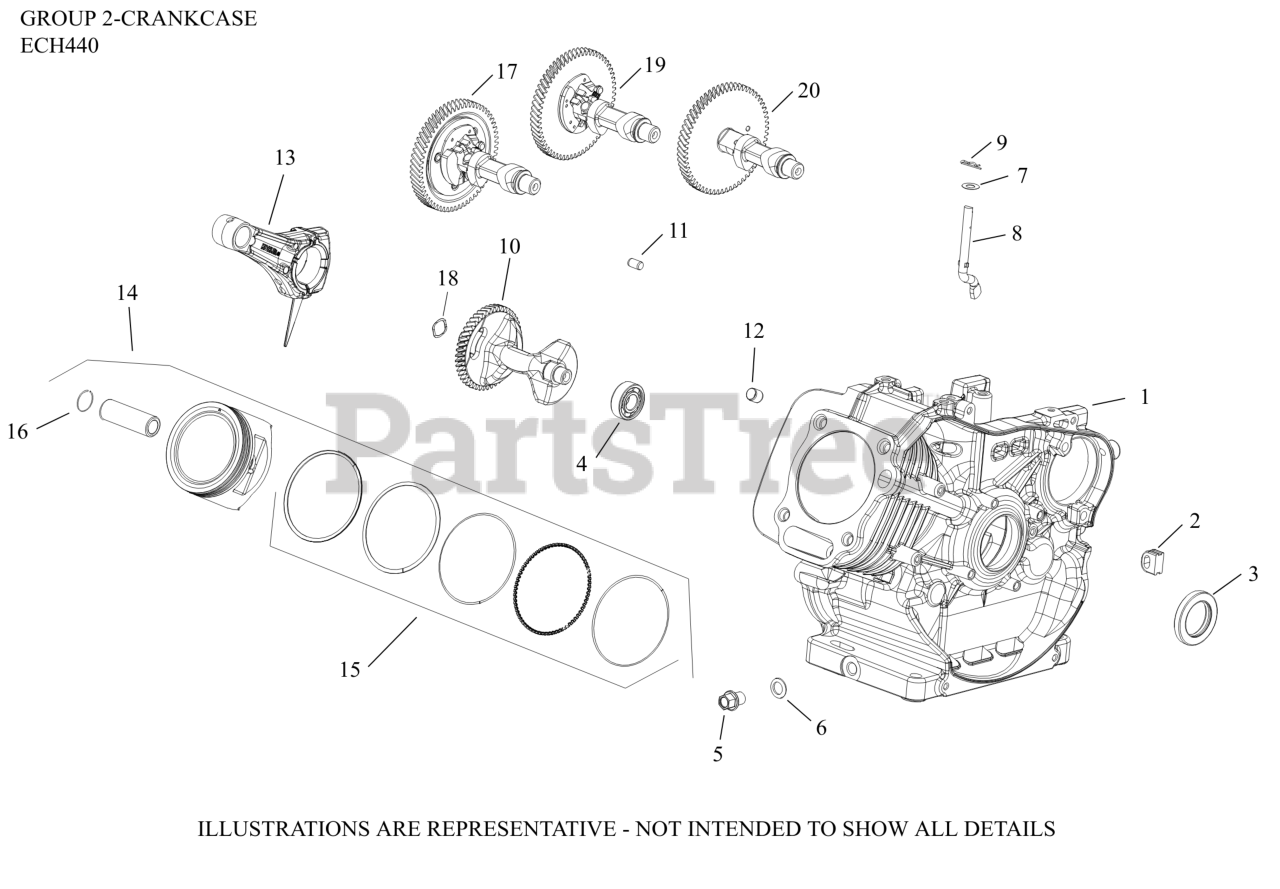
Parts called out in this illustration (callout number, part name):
2	GROMMET, CRANKCASE
3	SEAL, CRANKSHAFT
4	BEARING, BALANCE SHAFT
5	KIT, DRAIN PLUG
6	WASHER, DRAIN PLUG
10	SHAFT, BALANCE
11	PIN, DOWEL
12	PIN, DOWEL CYLINDER HEAD
13	ROD, CONNECTING ASSEMBLY
14	KIT, PISTON W/RING SET (STD)
14	KIT, PISTON (0.25 O.S.)
16	RETAINER, PISTON
17	CAMSHAFT ASSEMBLY
18	SPRING, WAVE
